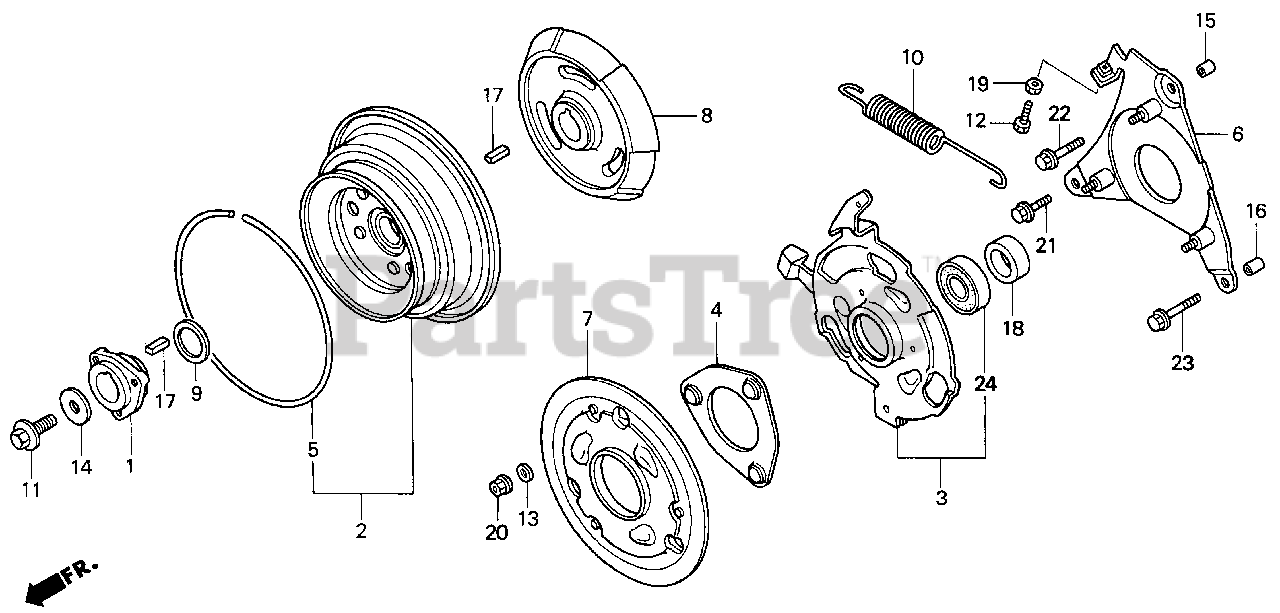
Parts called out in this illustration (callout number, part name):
1	BOSS, COOLING FAN
2	PULLEY ASSY., DRIVE
3	PLATE, BALL CONTROL
4	RETAINER, BALL
5	RING, P.T.O. CLUTCH
6	PLATE, BASE
7	PLATE, BRAKE
8	PLATE, DRIVE
9	COLLAR, DISTANCE (25MM)
10	SPRING, RETURN
11	BOLT, SPECIAL (8X30)
12	BOLT, ADJUSTING
13	WASHER (6X17X1.6)
14	WASHER, STEERING GEAR
15	PIN, DOWEL (10X23)
16	PIN, DOWEL (10X28)
17	KEY (7X7X18)
18	COLLAR, DISTANCE (25X35X13)
19	NUT, HEX. (8MM)
20	NUT, FLANGE (6MM)
21	BOLT, FLANGE (8X16)
22	BOLT, FLANGE (8X40)
23	BOLT, FLANGE (8X45)
24	BEARING, RADIAL BALL (6005UU)
